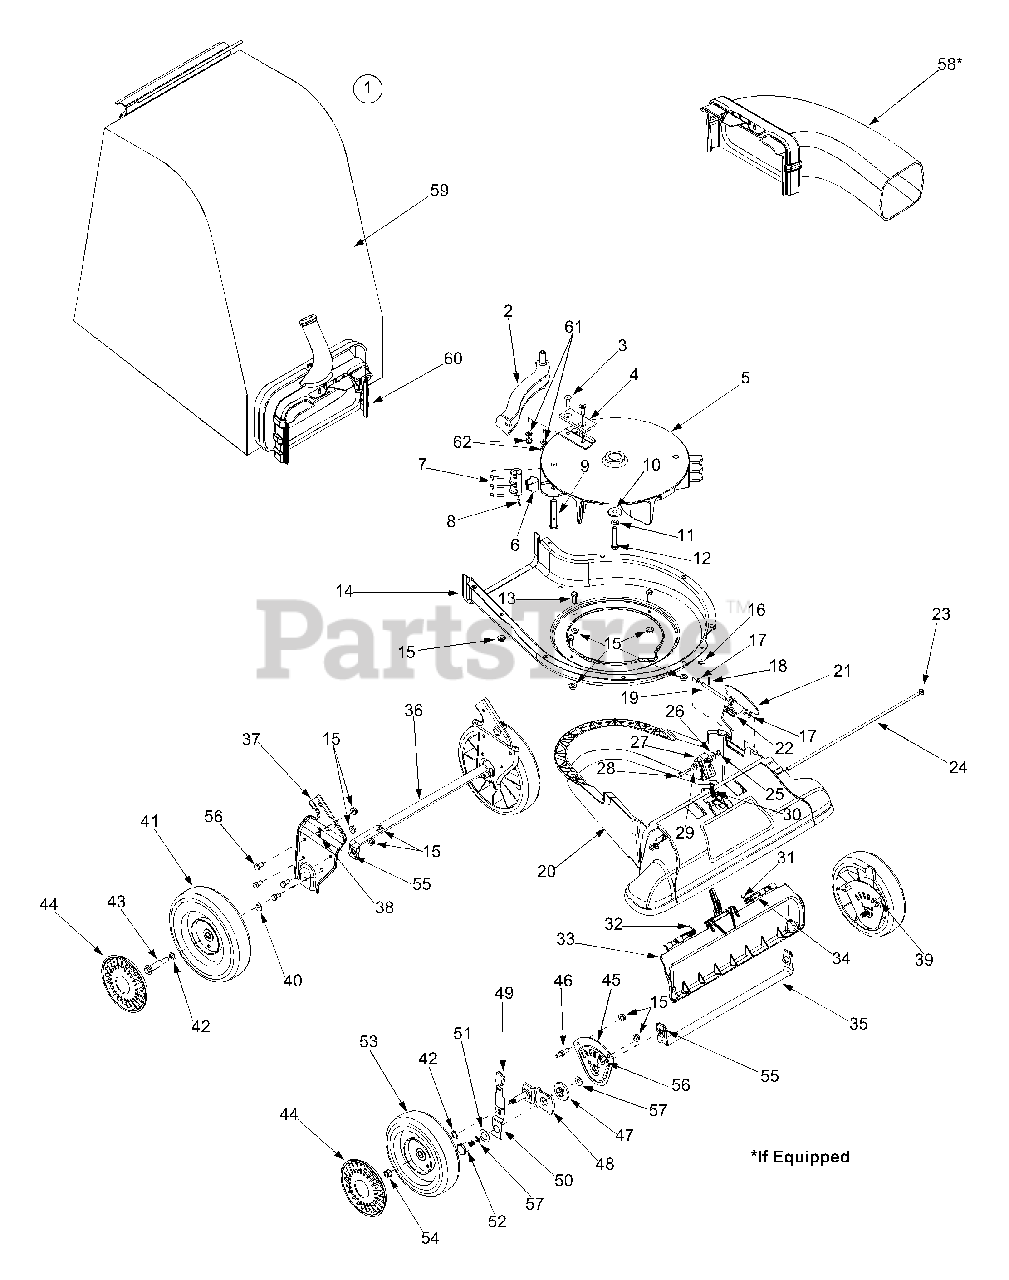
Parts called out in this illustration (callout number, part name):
1	Bag Assembly
3	Hex Screw 5/16-24 x 1.0
4	Chipper Blade
5	Impeller Assembly
7	Flail Blade
8	Spiral Pin
9	Clevis Pin
10	Flat Washer.375 ID x 1.25 OD
11	Lock Washer 3/8
12	Hex Cap Screw 3/8-24 x 2.0
13	Hex Cap Screw 5/16-18 x.875
15	Flange Lock Nut 5/16-18
16	Hex Flange Nut 1/4-20
17	Flat Washer.281 ID x.50 OD
18	Cotter Pin
19	Pivot Rod
20	Nozzle
21	Adapter Base Door
22	Torsion Spring
23	Cap Speed Nut 1/4
24	Pivot Rod
25	Hex Lock Nut #10-24
26	Flat Washer.194 ID x.62 OD
27	Nozzle Door Lever
28	Hex Screw #10-24 x 1.25
29	Shoulder Spacer
30	Extension Spring
31	Torsion Spring LH
32	Torsion Spring RH
33	Nozzle Door
34	Rod.25 x 1.25 Lg
38	Cotter Pin
39	Hex Cap Screw 5/16-18 x.625
40	Bell Washer.401 ID x.870 OD
41	Rear Wheel 9 x 2.125
42	Wave Washer.531 ID x.781 OD
43	Shoulder Screw 3/8-16
44	Hubcap
47	Height Adjustment Bearing
48	Pivot Arm Assembly
49	Height Adjustment Knob
50	Spring Lever
51	Bell Washer.760 ID x.25 OD
52	Shoulder Screw.750 ID x.625 OD
53	Front Wheel 8 x 2.125
54	Flange Lock Nut 3/8-16
55	Lock Nut 3/8-16
56	Screw 5/16-18 x.750
57	Thrust Washer.375 ID x.70 OD
58	Blower Chute
59	Bag
60	Chute Assembly
61	Lock Washer 5/16
62	Hex Lock Nut 5/16-24
